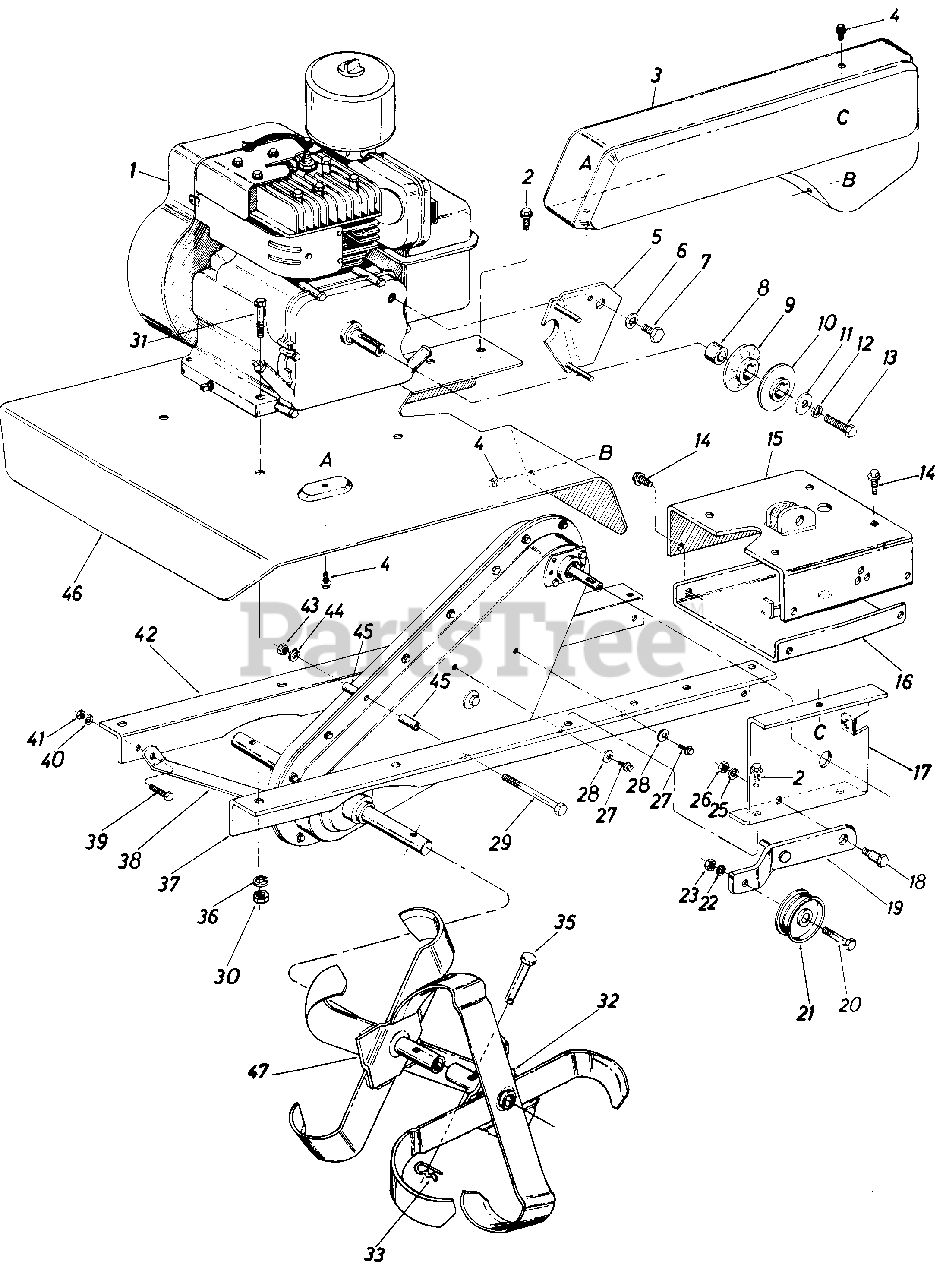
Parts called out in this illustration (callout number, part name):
1	Engine
2	Hex Wash. Hd. Self-Tap Scr. 5/16-24 x .50" Lg.
3	Belt Cover
4	Hex Wash. Hd. Self-Tap Scr. 1/4-20 x .50" Lg.
5	Belt Keeper Brkt. Ass'y.
6	Internal L-Wash. 1/2" I.D.
7	Hex Scr. 1/2-20 Thd.
8	Spacer
9	Pulley Half
10	Pulley Half
11	Fl-Wash. 3/8" I.D. x 1.25" O.D. x .100
12	L-Wash. 3/8" I.D.
13	Hex Scr. 3/8-24 x 1.00" Lg.
14	Hex Wash. Hd. Self-Tap Scr. 3/8-24 x 718" Lg.
15	Handle Mounting Brkt. Ass'y.
16	U-Channel Brkt. Ass'y.
17	Idler Mounting Brkt.
18	Shld. Bolt
19	Idler Brkt. Ass'y.
20	Hex Scr. 3/8-16 x 1.50" Lg.
21	Idler Pulley
22	L-Wash. 3/8" I.D.
23	Hex Nut 3/8-16 Thd.
25	L-Wash. 3/8" I.D.
26	Hex Nut 3/8-16 Thd.
27	Hex Wash. Hd. Self-Tap Scr. 1/4-20 x .50" Lg.
28	Belleville Wash. .26 I.D. x .75 O.D. x .060
29	Hex Scr. 5/16-18 x 2.75" Lg.
30	Hex Nut 5/16-18 Thd.
31	Hex Bolt 5/16-18 x 1.50" Lg.
32	See Tine Chart
33	Hairpin Cotter
35	Clevis Pin
36	L-Wash. 5/16" I.D.
37	Frame Rail-L.H.
38	Front Brace Brkt.
39	Hex Scr. 5/16-18 x .75" Lg.
40	L-Wash. 5/16" I.D.
41	Hex Cent. L-Nut 5/16-18 Thd.
42	Frame Rail-R.H.
43	Hex Cent. L-Nut 5/16-18 Thd.
44	L-Wash. 5116" I.D.
45	Spacer
46	Tine Shield
47	See Tine Chart
